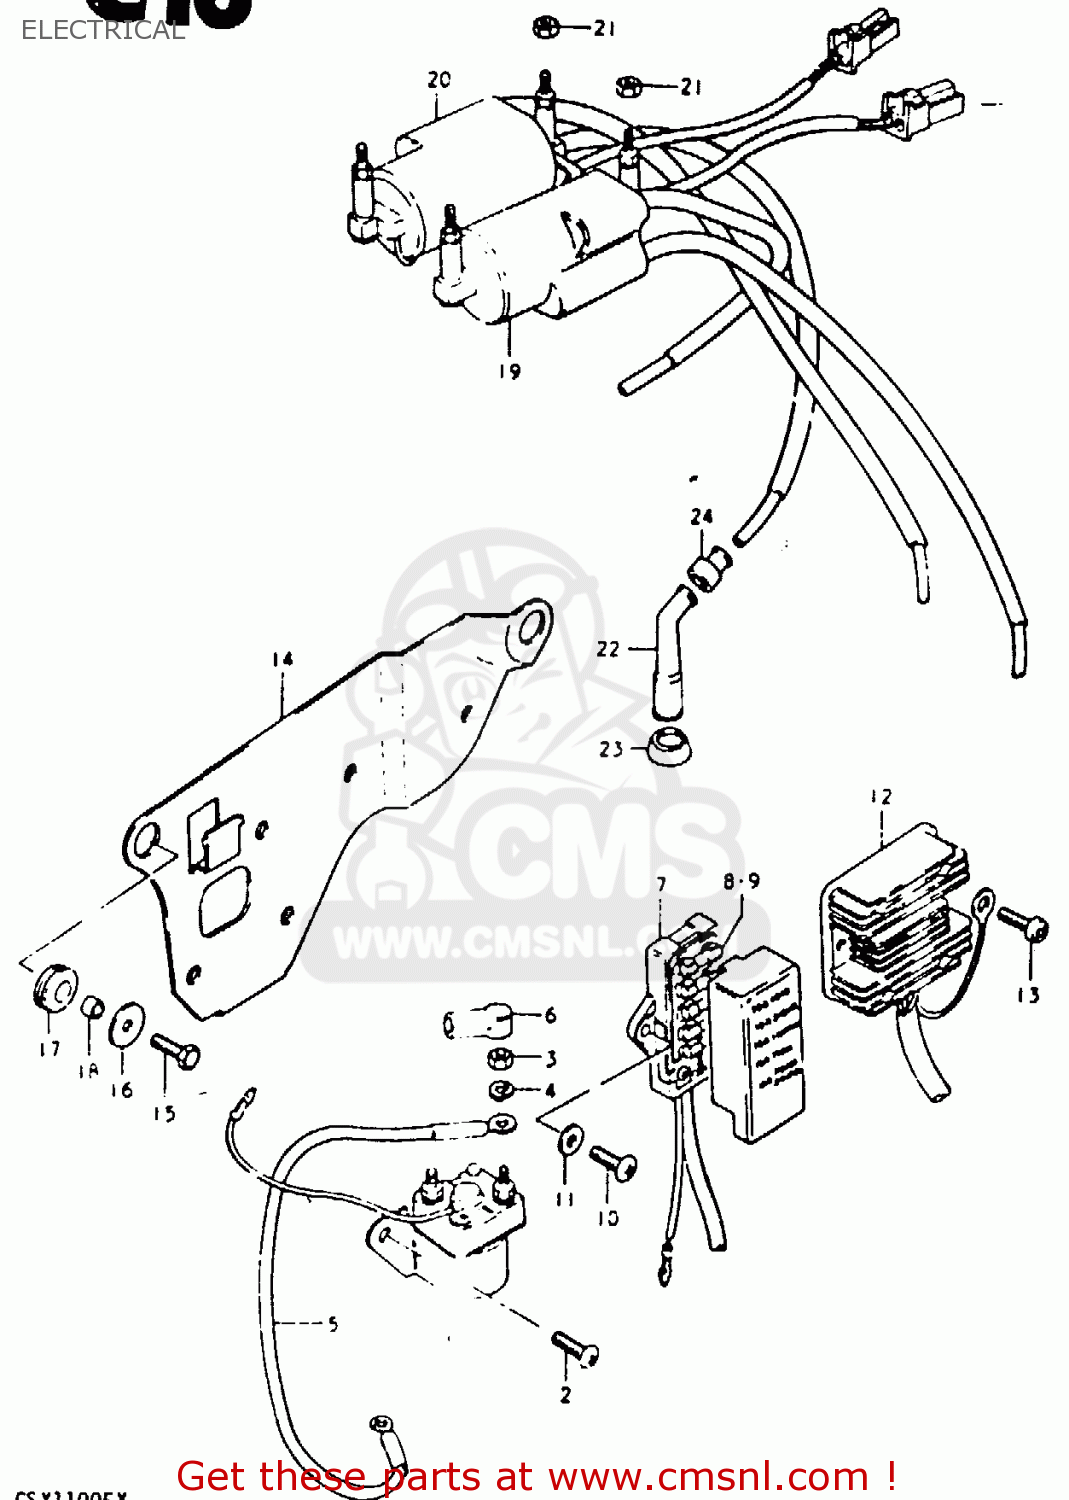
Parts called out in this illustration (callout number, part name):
1	RELAY ASSY,STARTING MOTOR
2	SCREW
3	NUT 6MM
4	LOCK WASHER
5	WIRE,STARTER MOTOR LEAD
6	CAP,STARTER RELAY
7	BOX ASSEMBLY,FUSE
8	FUSE(10A)
9	FUSE(15A)
10	SCREW
11	WASHER
12	RECTIFIER ASSEMBLY
13	SCREW 6X12
14	PLATE,ELECTRIC PARTS HOLDER
15	BOLT, UPPER
16	WASHER
17	CUSHION
18	SPACER (7X9X7)
19	COIL ASSEMBLY,IGNITION
20	COIL ASSEMBLY,IGNITION
21	NUT
22	CAP ASSY,SPARK PLUG
23	SEAL,SPARK PLUG
24	SEAL,SPARK PLU
